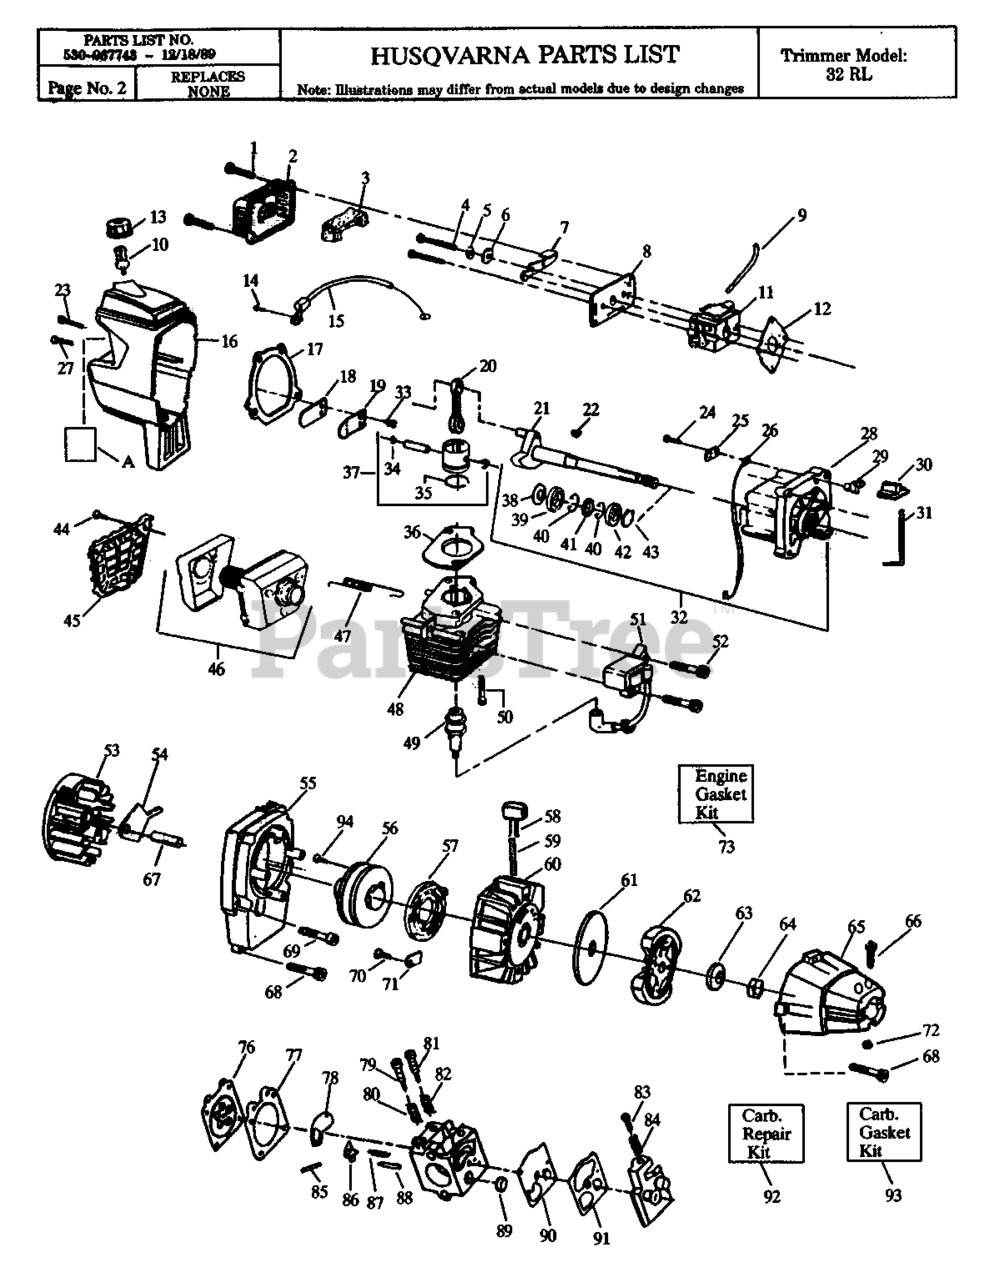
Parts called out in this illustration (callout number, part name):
1	SCREW-10-24 X 1" (TAP.)
2	COVER-FILTER
3	AIR FILTER
5	SPACER-CHOKE
7	SHUTTER-CHOKE
8	PLATE-AIR FILTER MTG.
9	HOSE. FUEL
10	ASSY-FUEL PICK-UP
11	CARBURETOR (WA-199)
12	GASKET-CARBURETOR
14	SCREW 8-16 X 9/16 (PLAS
15	ASSY-THROTTLE CABLE (SR
16	Shroud & Tank Ass'y.
17	GASKET-C'CASE/SHROUD
18	VALVE-REED
20	ASS'Y-CONNECTING ROD
21	ASSY-CRANKSHAFT
22	KEY-FLYWHEEL
23	SCREW-10-24 X 1" (TAP.)
24	SCREW 6-19X5/8 PLAS.PAN
25	INSULATOR-KILL SWITCH
26	LEAD WIRE-KILL SWITCH
27	SCREW 1/4-20 X 7/8 (TAP
28	Crankcase Ass'y.
29	KILL SWITCH RAMP
30	BUTTON-KILL SWITCH
31	SPRING-KILL SWITCH
32	ASSY-C'CASE & C'SHAFT
33	SCREW-6-19X5/16PLAST PA
34	WRIST PIN RET.
35	RING-PISTON (HOOKED)
36	GASKET-CYLINDER
37	KIT-PISTON (32CC)
38	SPACER-BEARING
39	Bearing-R8 (inner)
40	RING-RETAINING
41	SEAL-CRANKSHAFT
42	BEARING-R8 (OUTER)
43	RING-RETAINING (SHAFT)
44	SCREW-10-16X9/16SLTD.PH
45	GUARD-MUFFLER
46	KIT-MUFFLER ASS'Y
47	SPRING
48	CYLINDER
49	SPARK PLUG (RCJ-8)
50	SCREW-1/4-20 X 13/16
51	MODULE-IGNITION
52	SCREW-COIL MTG
53	ASSY-FLYWHEEL
54	COUNTERWEIGHT FLYWL 26RLC
55	HOUSING-FAN (ORANGE)
56	KIT-STARTER PULLEY
57	SPRING-STARTER
58	HANDLE-STARTER
60	ASSY-PULLEY HSG (ORANGE
61	WASHER-CLUTCH
63	WASHER-BELLEVILLE
65	ASSY-CLUTCH HSG (ORANGE
66	SCREW-10-24 X 1-3/8 (UN
67	SPACER-CLUTCH
69	SCREW-10-24X1-3/8-TAPTI
70	SCREW-10-16 X 1/2 HI-LO
72	LOCKNUT-HEX 10-24
73	KIT-GASKET
76	DIAPHRAGM
77	GASKET-METER DIAP
78	GASKET-CIRCUIT PLATE
79	HI-SPEED NEEDLE
80	Hi Speed Needle Spring
81	NEEDLE - IDLE
82	SPRING-NEEDLE FUEL MIX
83	SCREW-IDLE SPEED
84	SPRING-IDLE SPEED
85	PIN
86	Metering Lever
87	SPRING-METERING LEVER
88	INLET NEEDLEVALVE
89	SCREEN-DUTCH TWILL INLE
90	DIAP FUEL PUMP
91	GASKET-FUEL PUMP
92	REPAIR KIT
93	KIT-KWIK REPAIR
94	SCREW-6-19X9/32 PAN/SEM
A	DECAL
